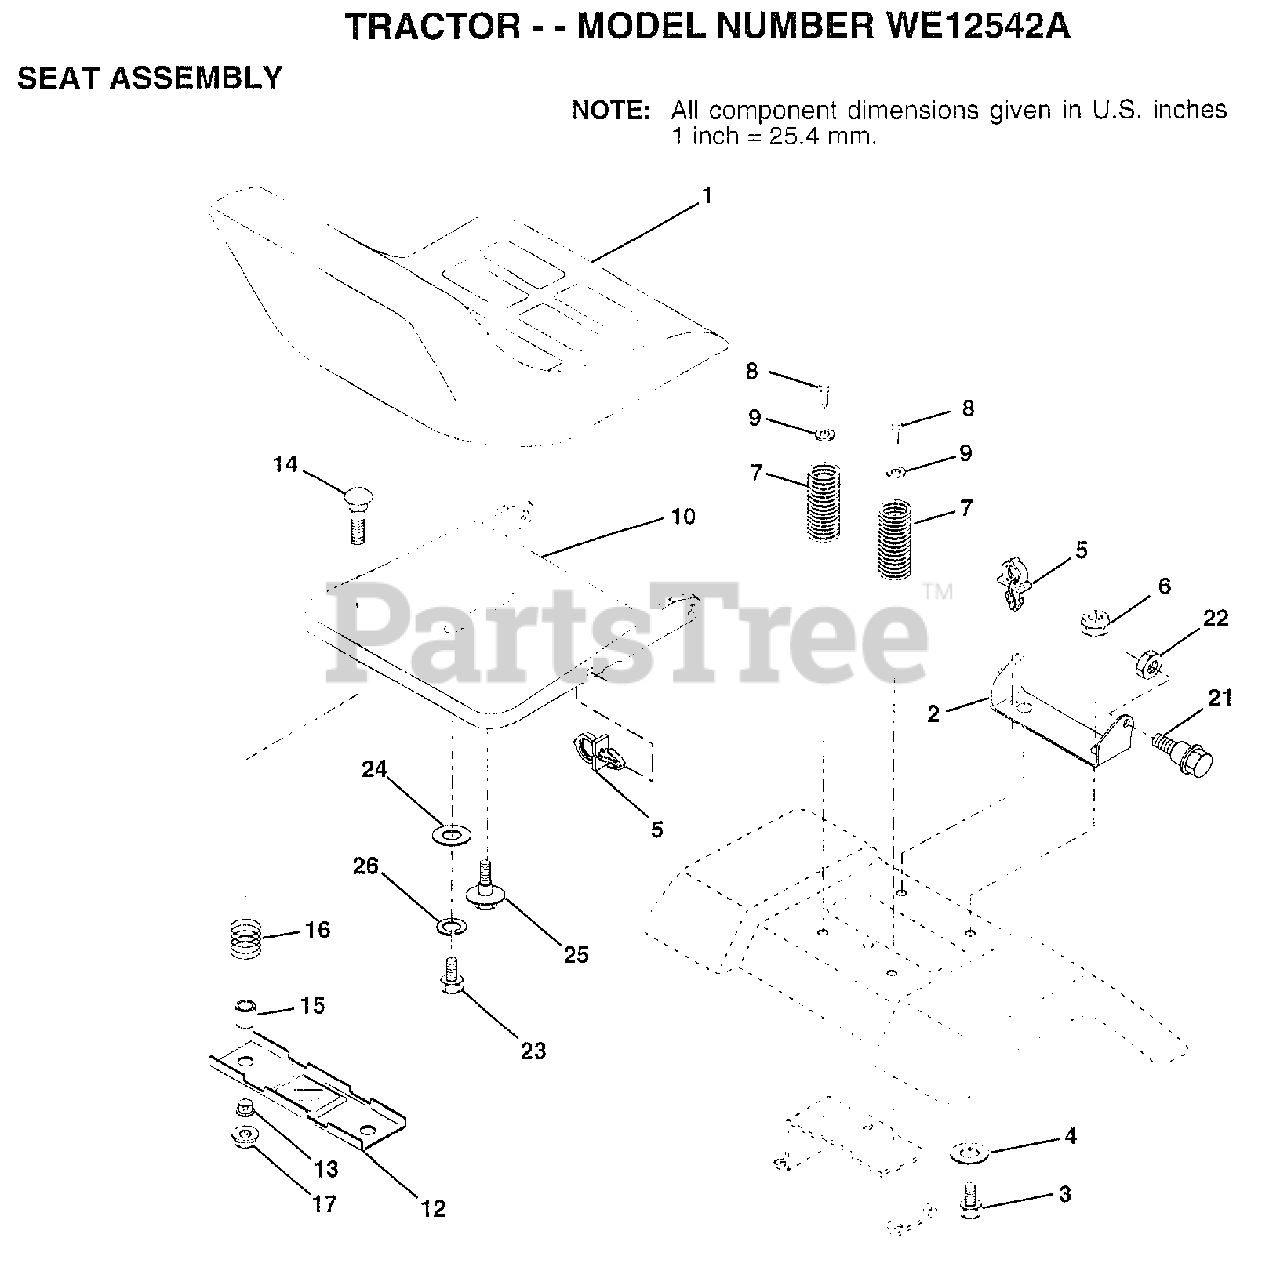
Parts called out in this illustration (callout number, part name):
2	BRACKET PVT SEAT
3	BOLT
4	WASHER PM
5	CLIP.PUSH-IN.HING
6	NUT
7	SPRING COMPRESSIO
8	SCREW GTV
9	WASHER
10	PAN-SEAT
12	BRKT SWITCH
13	BUSHING
14	BOLT-RD HD SQ NK
15	SPLIT SPACER
16	SPRING
21	"BOLT,SHOULDER"
22	NUT
23	BOLT
24	WASHER
25	"BOLT,SHOULDER"
26	LOCKWASHER
